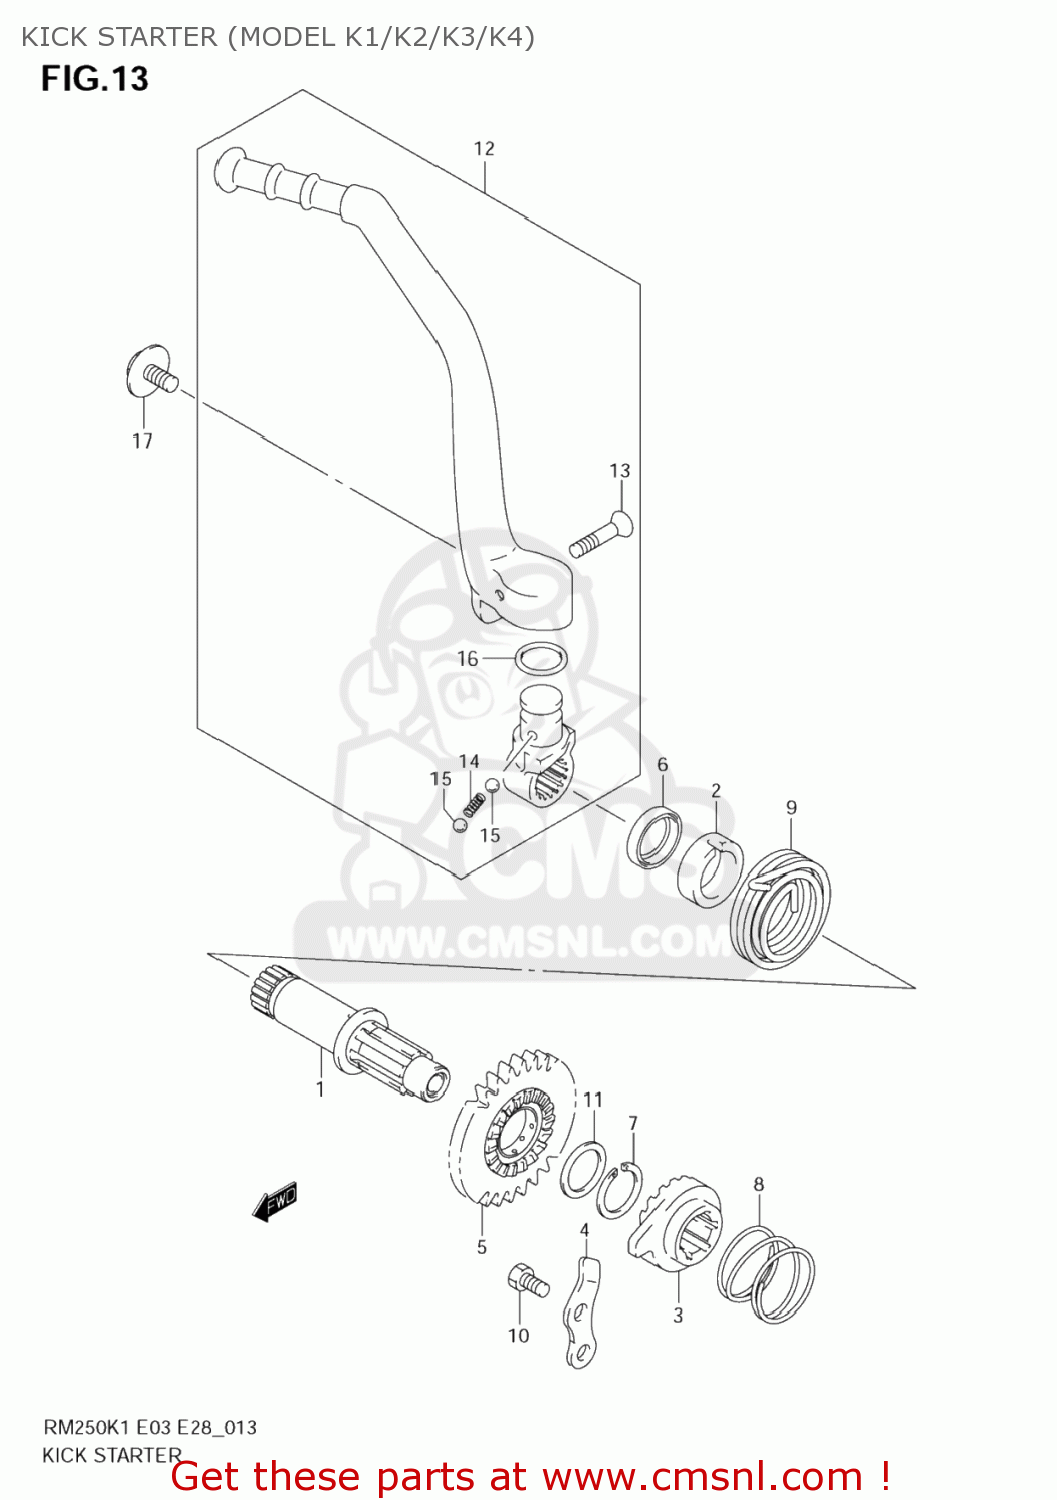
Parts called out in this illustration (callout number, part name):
1	SHAFT,KICK STARTER
2	GUIDE,KICK STARTER SHAFT
3	STARTER,KICK
4	GUIDE,KICK STARTER
5	GEAR,KICK STARTER DRIVE(NT:28)
6	SEAL,OIL(20X27X5)
7	CIRCLIP
8	SPRING
9	SPRING
10	BOLT
11	SHIM(22X28X1)
12	LEVER ASSY,KICK STARTER
13	SCREW(6X27.5)
14	SPRING
15	BALL
16	O RING,KICK STARTER
17	BOLT(8X14)
